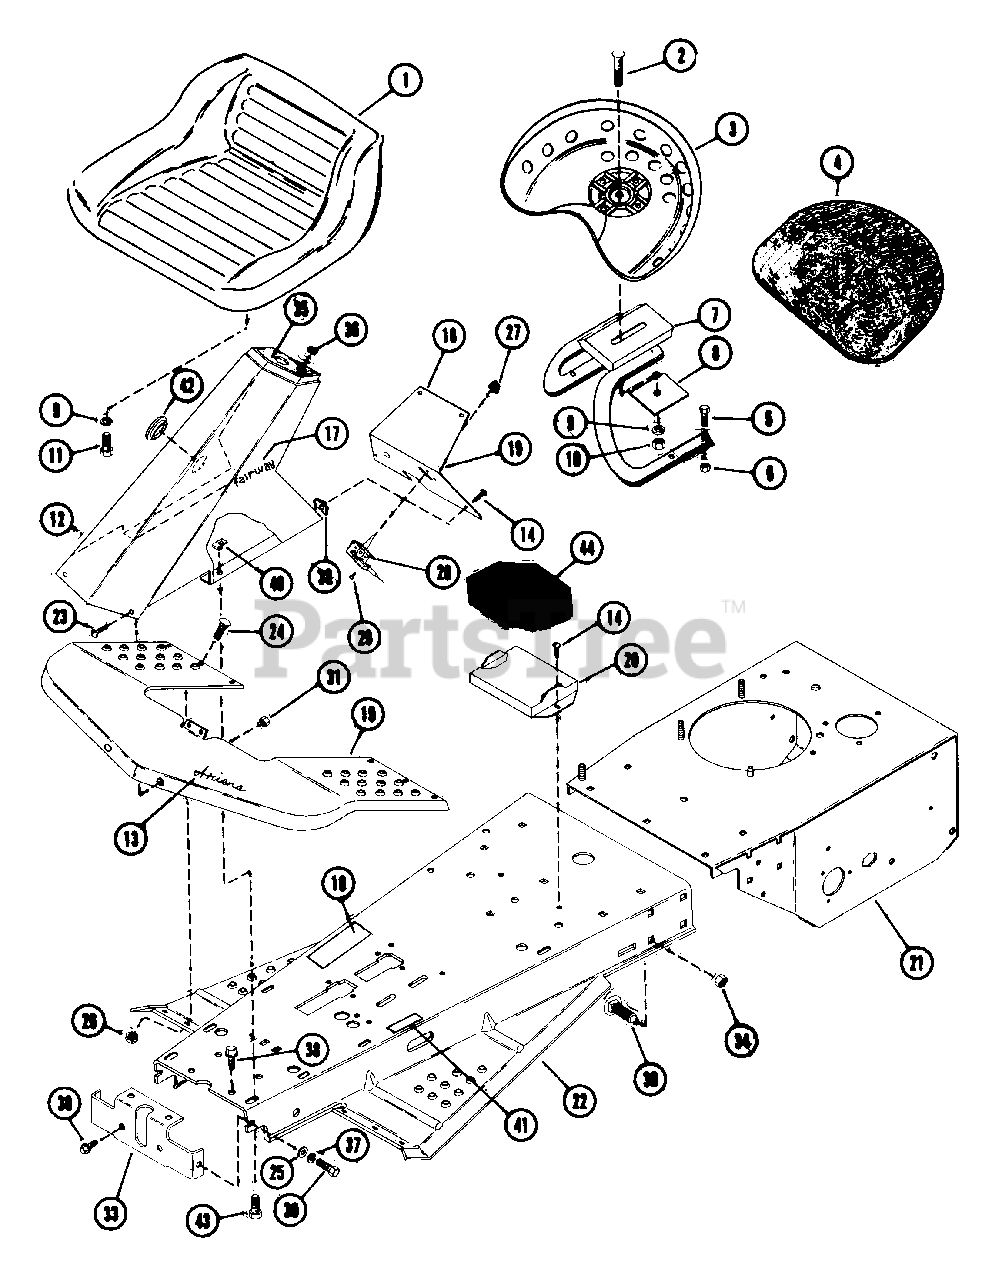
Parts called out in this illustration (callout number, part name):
1	SEAT
2	BLT-RDHDSQNK .50-13X1.25 PL
3	SEAT
4	SEAT COVER
5	BLT-HEX .31-18X1.50 PL GR2
6	NUT-LK .312-18 GR A PL
7	SEAT BRACKET
8	SEAT SUPPORT WASHER
9	WSHR-LK .500X.151 HVY PL
10	NUT .50-13 PL
11	BLT-HEX .50-13X1.25 PL GR2
12	STEERING COLUMN
13	ARIENS NAME PLATE
14	SCR-TAP 10-12X.50 CRPH PL A
15	FRONT FENDER
16	DASH PANEL ASSEMBLY
17	FAIRWAY NAME PLATE
18	CAUTION DECAL
19	DASH DECAL
20	BATTERY RETAINER
21	REAR FRAME
22	FRONT FRAME ASSEMBLY
23	SCR-MCH 10-24X.38 SLTOR PAN PL
24	SCR-SLTR-SERNK .25-20X.62 PL
25	WSHR-FL-STL .38X.875X.083 PL
26	NUT-LK-FLG .250-20 PL
28	THROTTLE CONTROL
29	RVT-POP.125 X .294 DOME
30	BLT-HEX .31-18X.75 PL GR2
31	NUT-LK DUAL FACE 10-24 PL
32	NUT-SPEED U TYPE 10A
33	FRONT FRAME SUPPORT
34	NUT-FLG. .312-18 PL
35	PARKING BRAKE DECAL
36	GROMMET, .31 ID
37	WSHR-LK .312X.097 PL HVY
38	BLT-LK .31-18X.75 GR 5
39	BLT-RDHDSQNK .31-18X.75 GR5 PL
40	NUT-SPEED U-TY .312-18
41	MOWER IN-OUT LABEL
43	BLT-HEX .31-18X.50 PL GR2
44	RUBBER PAD
